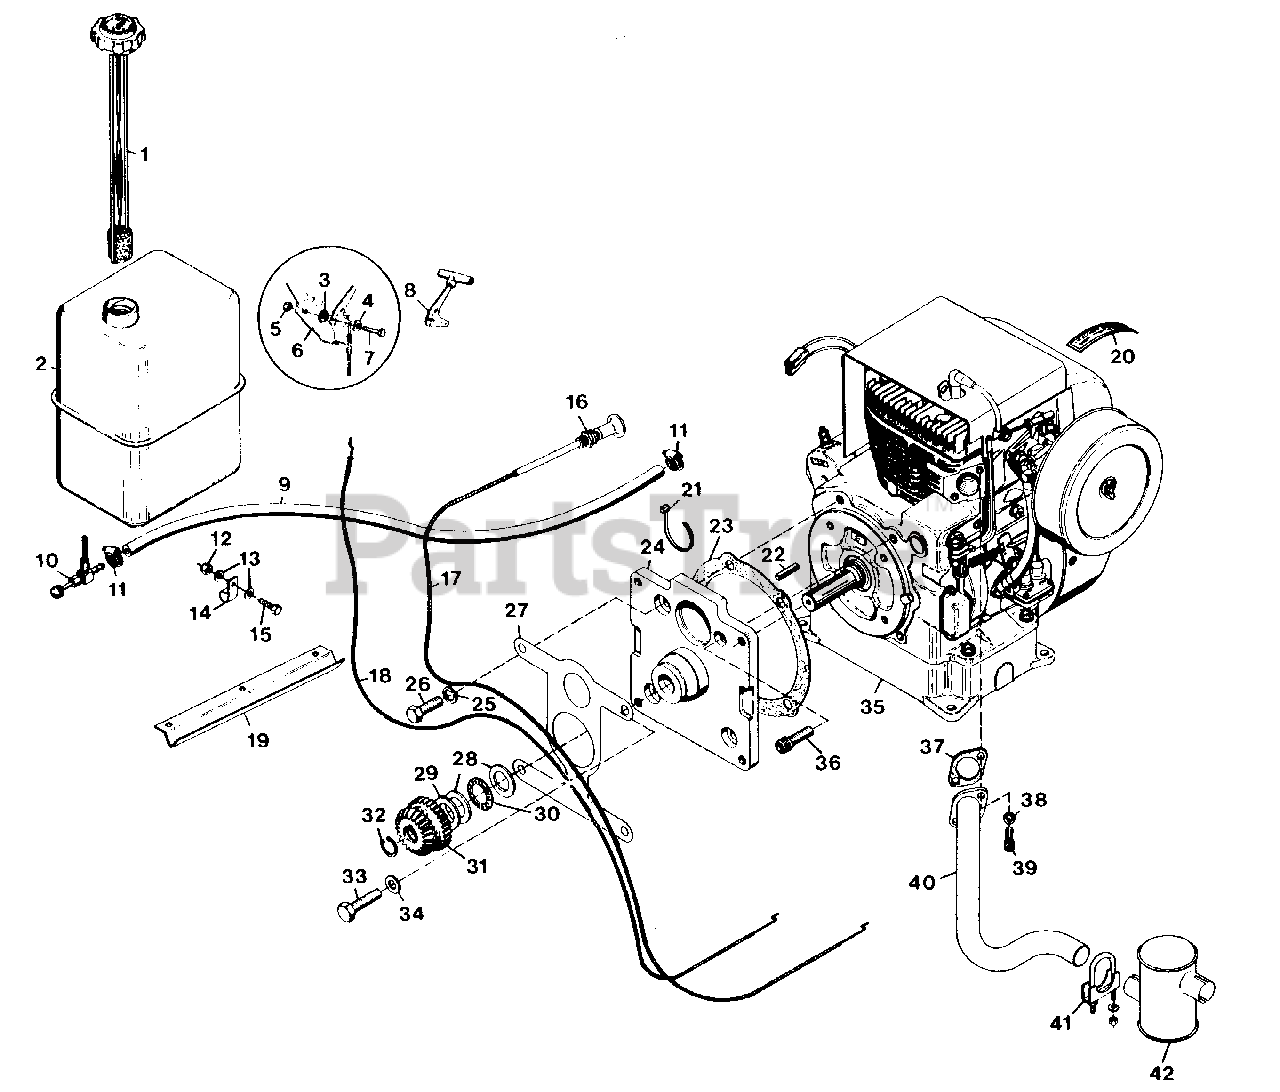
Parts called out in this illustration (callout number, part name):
1	GAUGE, GAS
2	TANK, FUEL
3	WASHER, FRICTION
4	WASHER, SPRING
5	NUT, LOCK 1/4-28
6	BRACKET, MOUNTING
7	BOLT, HEX 1/4-28X.75
8	ASSEMBLY, KNOB AND LEVER
9	LINE, FUEL
10	VALVE, FUEL 90 DEG. REVERSE FLOW
11	CLAMP, HOSE
12	NUT, LOCK 5/16-18
13	WASHER, FLAT .344X.688X.065
14	CLAMP, NYLON
15	BOLT, HEX 5/16-18X1.00
16	NUT, JAM 3/8-24
17	CONTROL, CHOKE
18	ASSEMBLY, CHOKE CONDUIT
19	SHIELD, HEAT
20	DECAL, AIR CLEANER INSTRUCTION
21	TIE, CABLE
22	KEY, SQUARE .250X1.250
23	GASKET, ADAPTOR
24	ADAPTOR, ENGINE
25	WASHER, LOCK 7/16 SP HEAVY
26	BOLT, HEX 7/16-14X1.125
27	GASKET, ENGINE TO TRANSMISSION
28	RACE, BRG 1.125X1.75X.123/.126
29	SHIM, 1.125X1.750X.030
30	BEARING, THRUST 1.127X1.740X.078
31	GEAR, SPUR AND BEVEL, INPUT
32	RING, RETAINING 1.125 SHAFT
33	BOLT, HEX 1/2-13X1.25
34	WASHER, LOCK 1/2 REG.
35	ENGINE, 12 HP ELECTRIC 4-WHEEL
36	SCREW, CAP 7/16-14X1.0 SHD
37	GASKET, EXHAUST
38	WASHER, LOCK 5/16 REG.
39	SCREW, CAP 5/16-18X.75 S/HD
40	HEADER, EXHAUST
41	CLAMP, MUFFLER
42	MUFFLER, EXHAUST
NS	NUT, LOCK 10-32
NS	SCREW, MACHINE 10-32X.50 PHD
